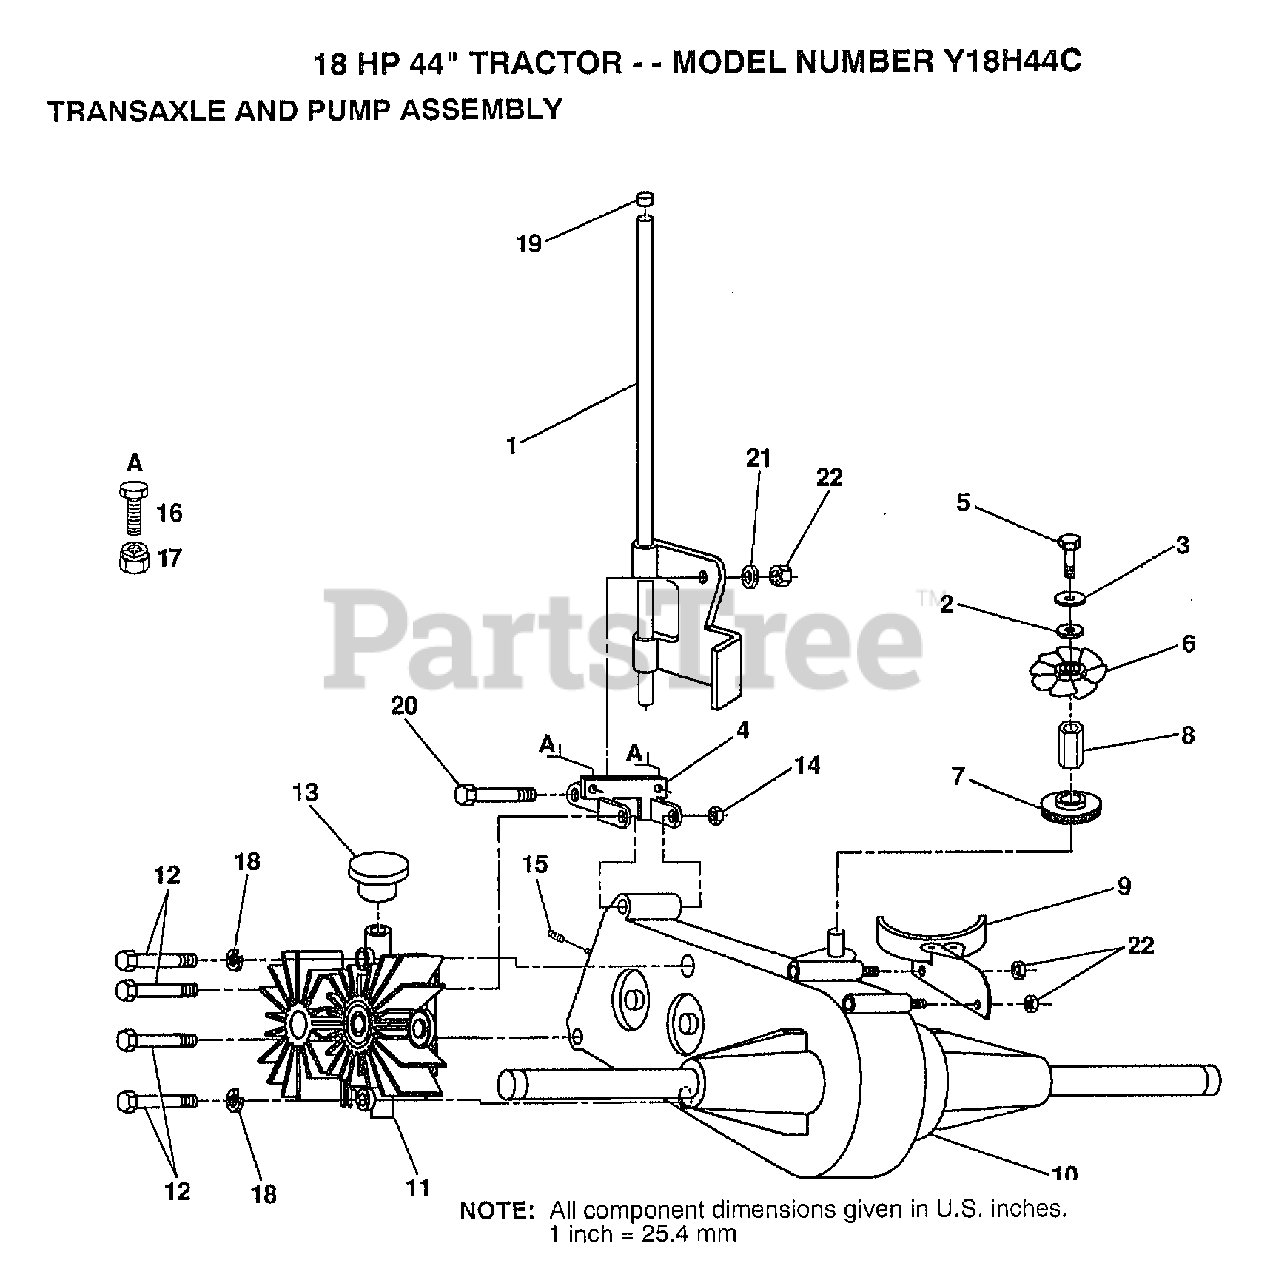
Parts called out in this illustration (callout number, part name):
1	CONTROL ASSY
2	WASHER
3	LOCKWASHER
4	BRACKET
6	FAN
7	PULLEY TRANSAXLE
8	STANDOFF
9	GUARD ASSY
10	TRANSAXLE.AGRIFAB
11	PUMP.BDU-10S-114
12	BOLT
13	PUMP.2003081.
15	SPRING
18	LOCKWASHER
19	PLUNGER CAP T
20	BOLT T
21	WASHER T
